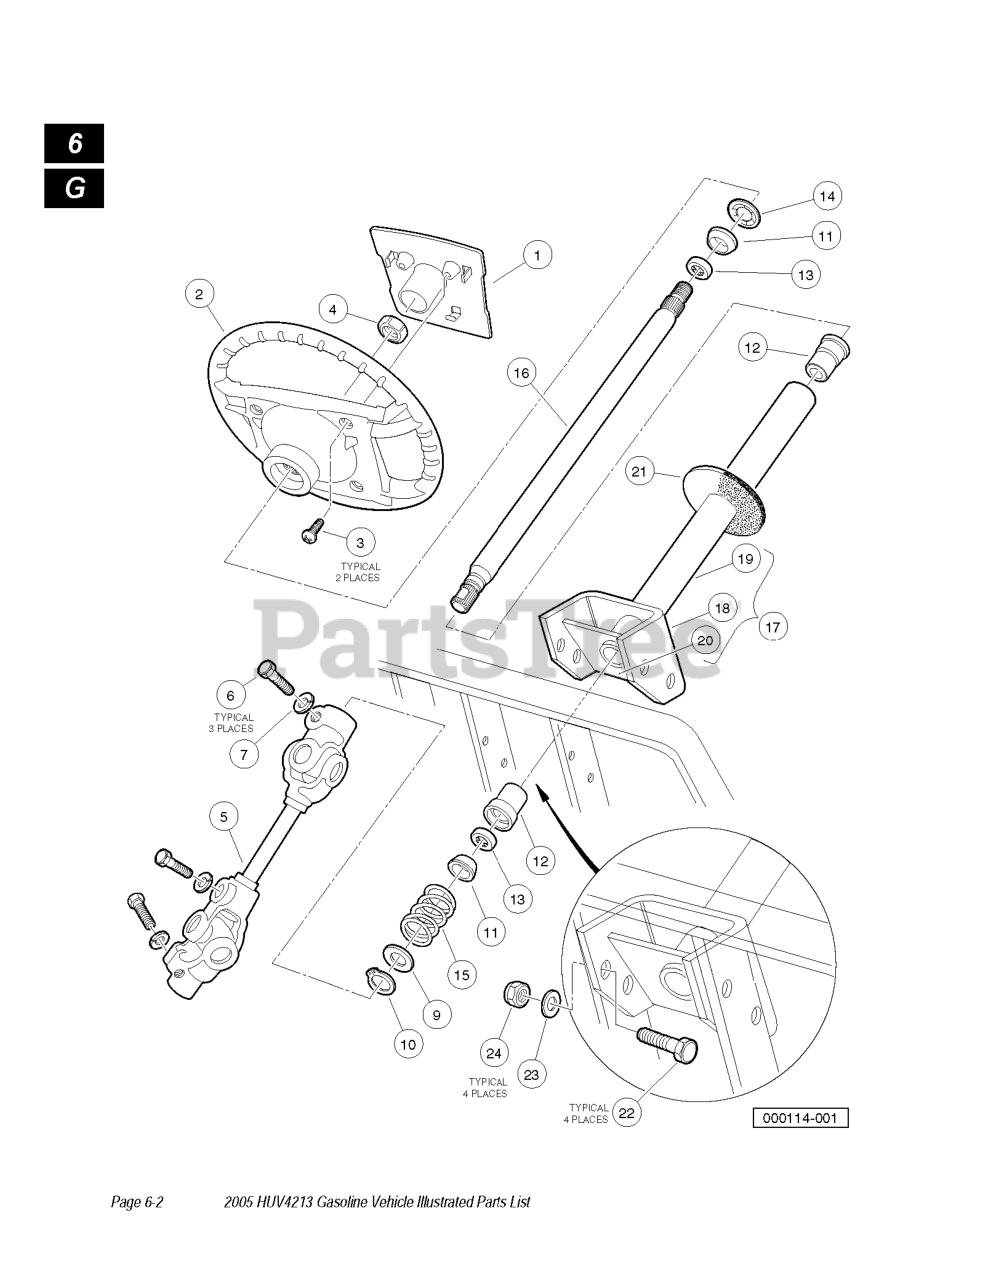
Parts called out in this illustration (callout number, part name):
2	WHEEL ASSY, SPL. HUB STEERING
3	SCREW, #12-14 X .625 TYP AB PN
4	NUT, 5/8-18 NYLON INSERT JAM
5	YOKE ASSEMBLY
6	HEX HEAD BOLT, 8MM X 1.25 - 30
7	LOCKWASHER, 5/16 SPLIT
8	STEERING COLUMN
11	WEDGE MOLDED
12	SEAT, PLASTIC BEARING
13	BEARING ASSY STEERING SHAFT
14	RING, RETAINING
15	SPRING, STEERING SHAFT COMP
16	SHAFT STEERING COLUMN
17	COLUMN WELD ASSY, STEERING
18	Column Mtg Bracket
19	Steering Column
20	Steering Column
21	BOOT, STEERING COLUMN ROUND
22	SCREW, CAP, HEX HD 3/8-16X1.00
23	WASHER, 3/8 FLAT
24	LOCKNUT, 3/8-16 HEX
